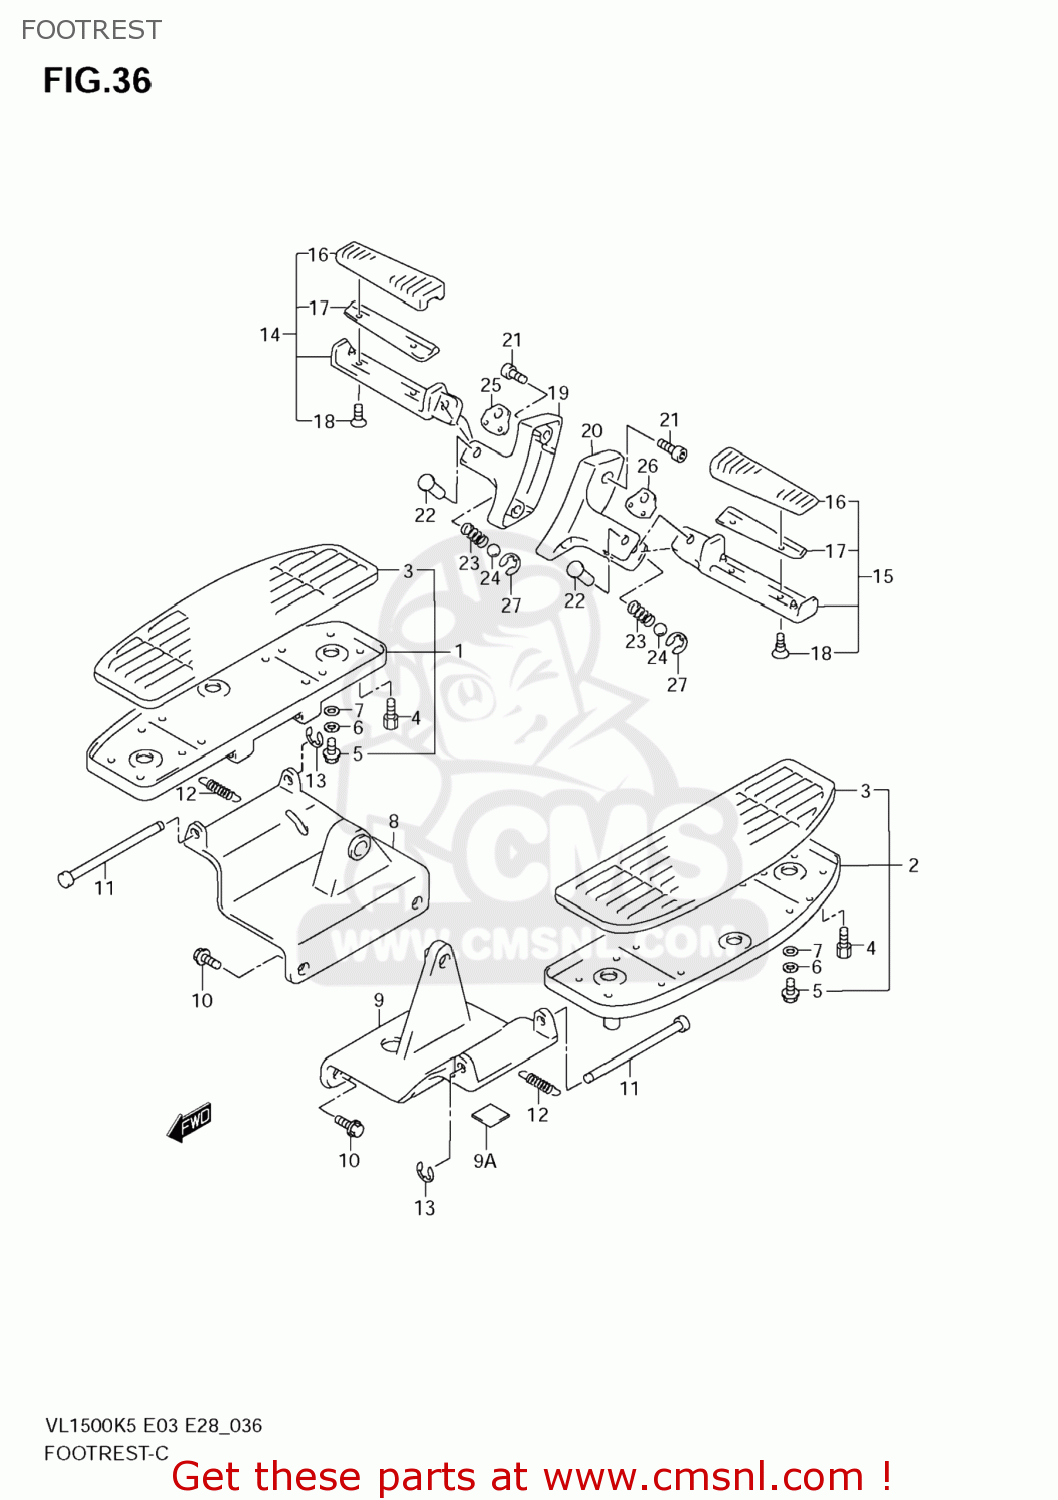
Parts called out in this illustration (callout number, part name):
1	FOOTREST ASSY,
2	FOOTREST ASSY,
3	RUBBER,FR FOOTREST
4	BOLT,BANK SENSOR
5	BOLT
6	WASHER(6.5X22X1.6)
7	CUSHION
8	BRACKET,FR FOOTREST,R
9	BRACKET,FR FOOTREST,L
9A	CUSHION
10	BOLT
11	PIN,FR FOOTREST
12	SPRING
13	E RING
14	FOOTREST ASSY,PILLION,R
15	FOOTREST ASSY,PILLION,L
16	RUBBER,PILLION FOOTREST
17	PLATE,RUBBER STOPPER
18	SCREW(5X16)
19	BRACKET,PILLION FOOTREST,R
20	BRACKET,PILLION FOOTREST,L
21	BOLT
22	PIN(8X33.2)
23	SPRING
24	BALL
25	PLATE,PILLION FOOTREST,R
26	PLATE,PILLION FOOTREST,L
27	E RING
